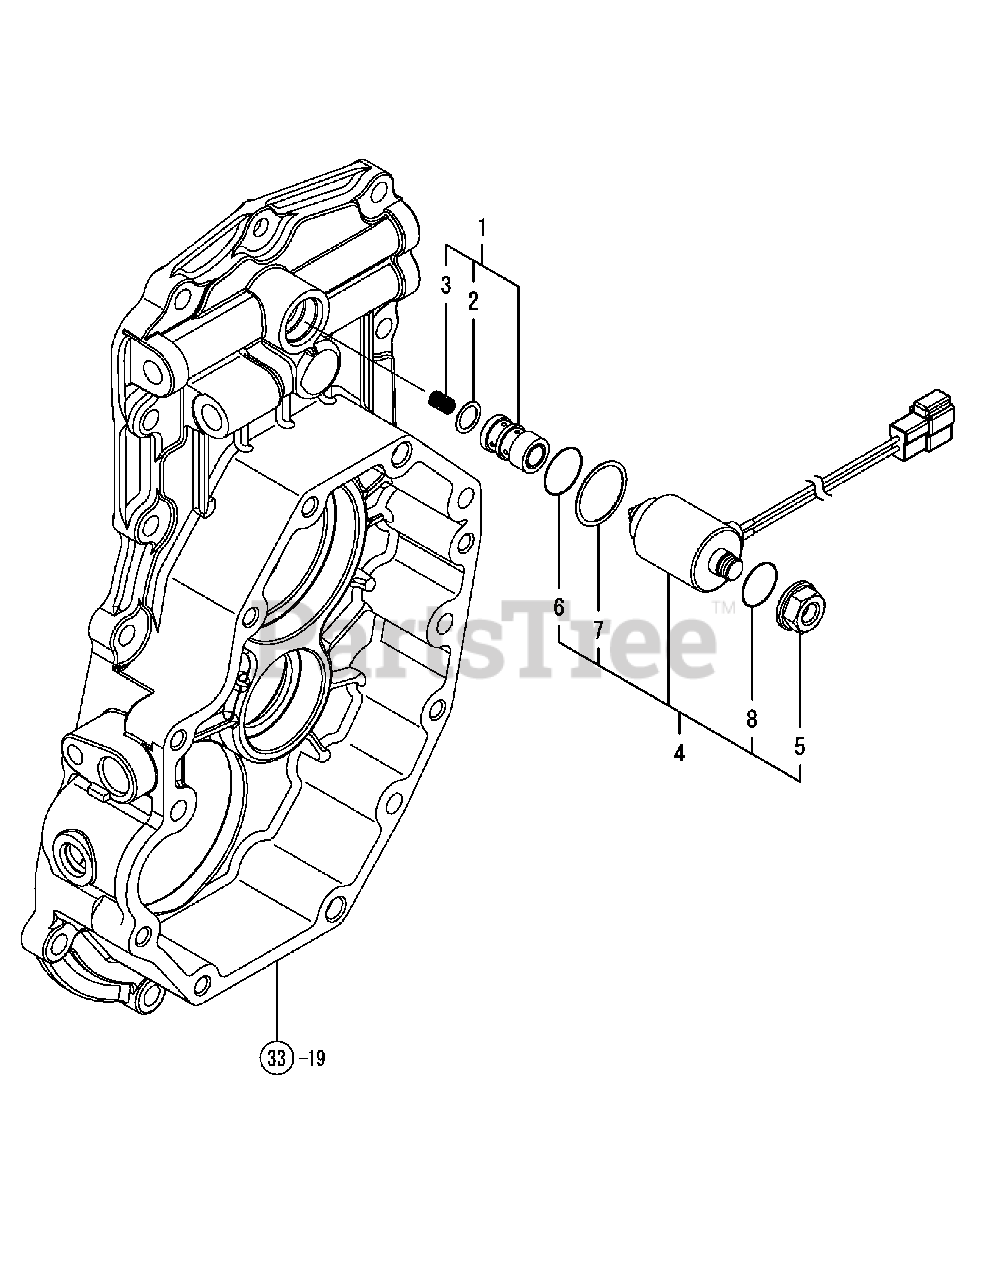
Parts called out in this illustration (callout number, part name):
1	VALVE SOLENOID CMP
3	SPRING, SOLENOID
6	O-RING 1A P-18.0
7	GASKET, SOLENOID
8	O-RING 1A S-11.2
